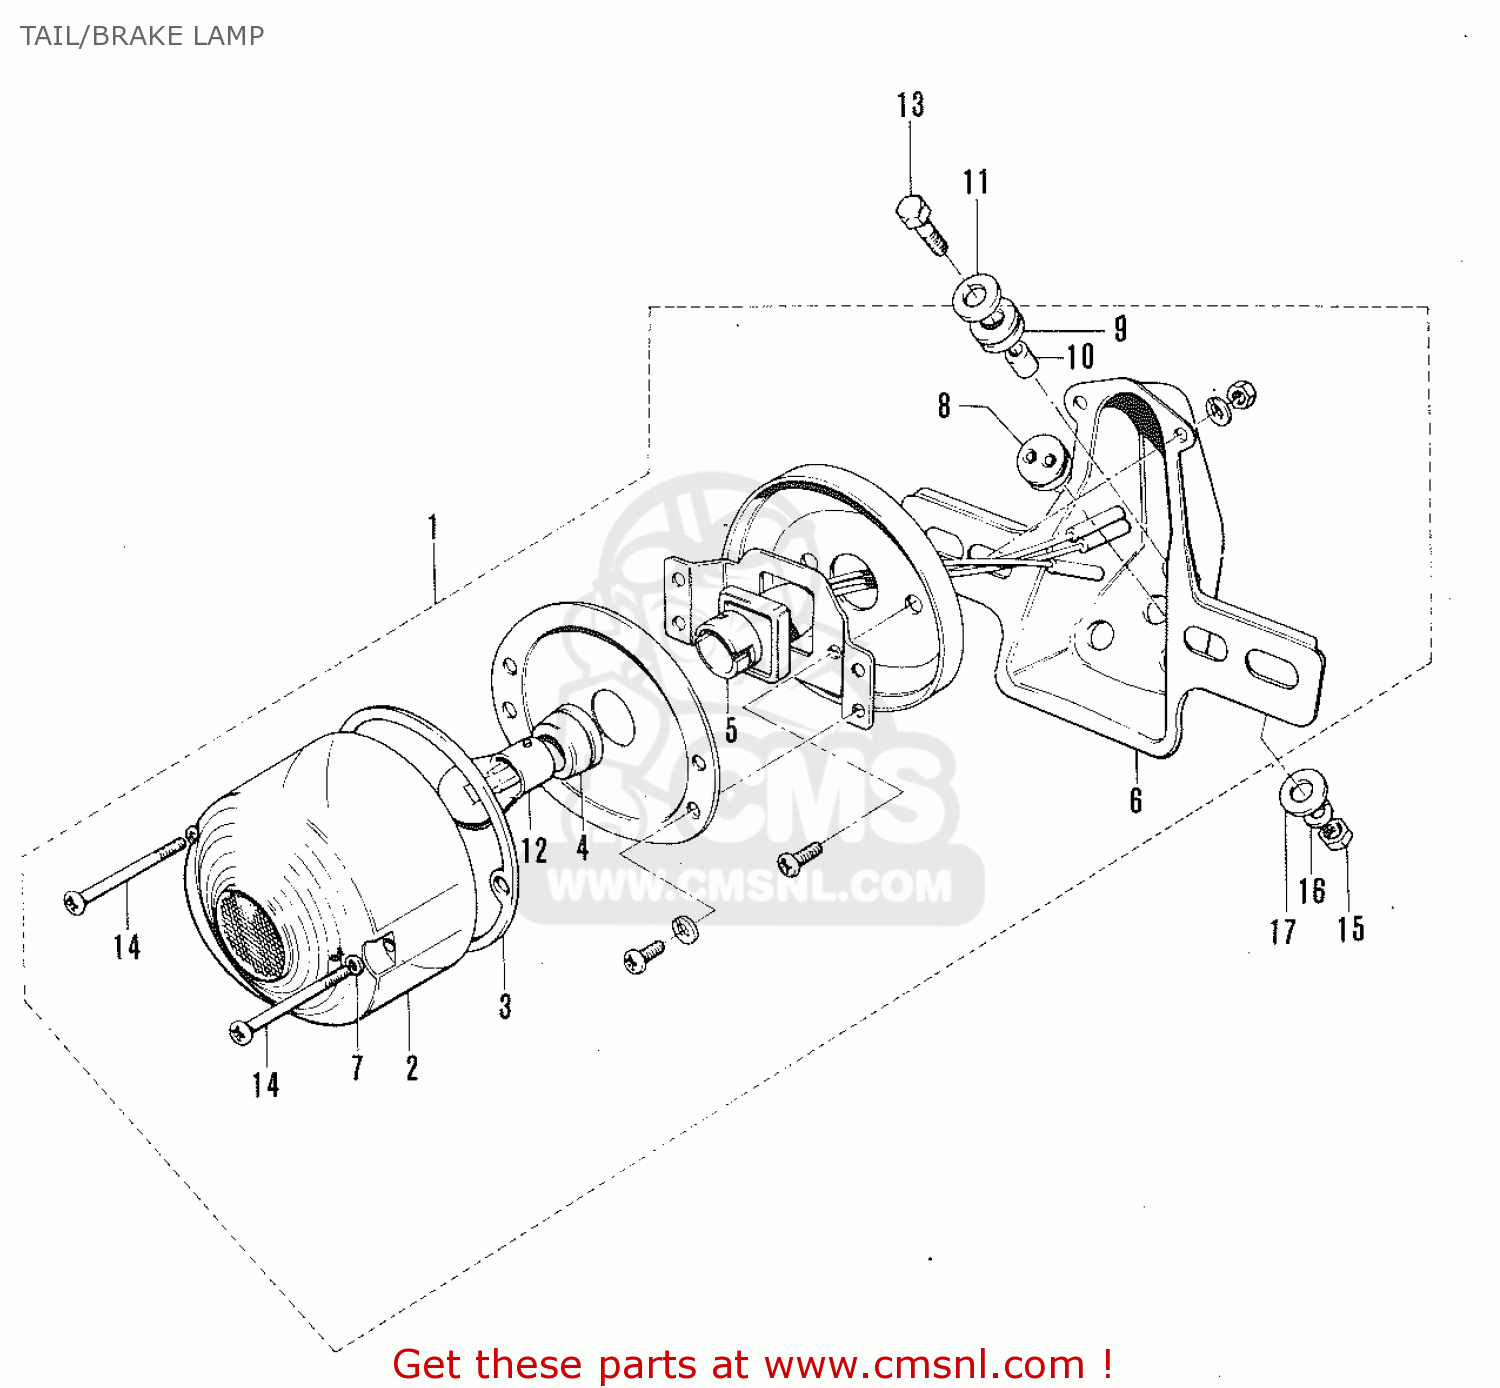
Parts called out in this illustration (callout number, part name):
1	LAMP ASSEMBLY,REAR COMBINATION
2	LENS,REAR COMBINATION LAMP
3	GASKET,REAR COMBINATION LAMP LENS (NAS)
4	PLATE,REAR COMBINATION LAMP
5	SOCKET
6	BRACKET,REAR COMBINATION LAMP
7	WASHER,REAR COMBINATION LAMP
8	GROMMET,REAR COMBINATION LAMP
9	CUSHION
10	SPACER,REAR COMBINATION LAMP
11	WASHER
12	BULB(6V17/5.3W,STANLEY,A4813)
13	BOLT
14	SCREW
15	NUT
16	LOCK WASHER
17	WASHER
